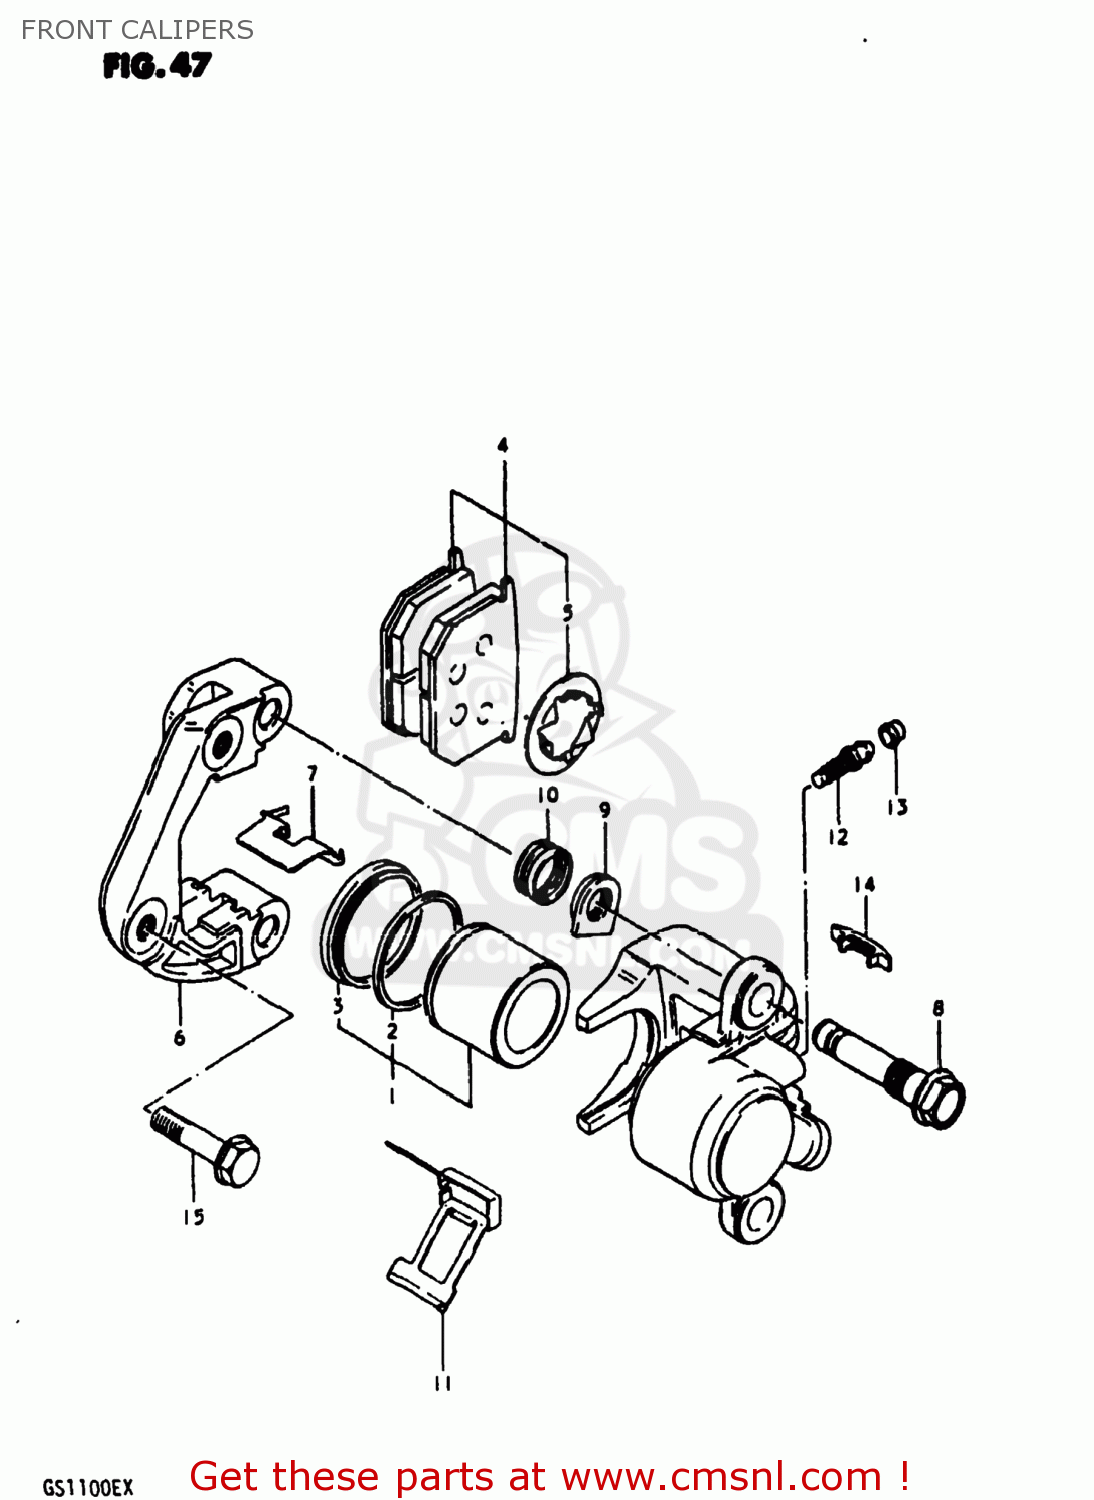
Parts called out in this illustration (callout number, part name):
0	CALIPERS ASSY, RH
1	PISTON SET
2	SEAL,PISTON
3	BOOT,PISTON
4	PAD & SHIM SET (MCA)
5	SHIM,PAD
6	HOLDER,CALIPER,LEFT
7	GUIDE,PAD
8	AXLE,CALIPER
9	NUT,CALIPER AXLE
10	SPRING
11	SPRING
12	BREATHER
13	CAP,BLEEDER PL
14	COVER,INDICATOR
15	BOLT
